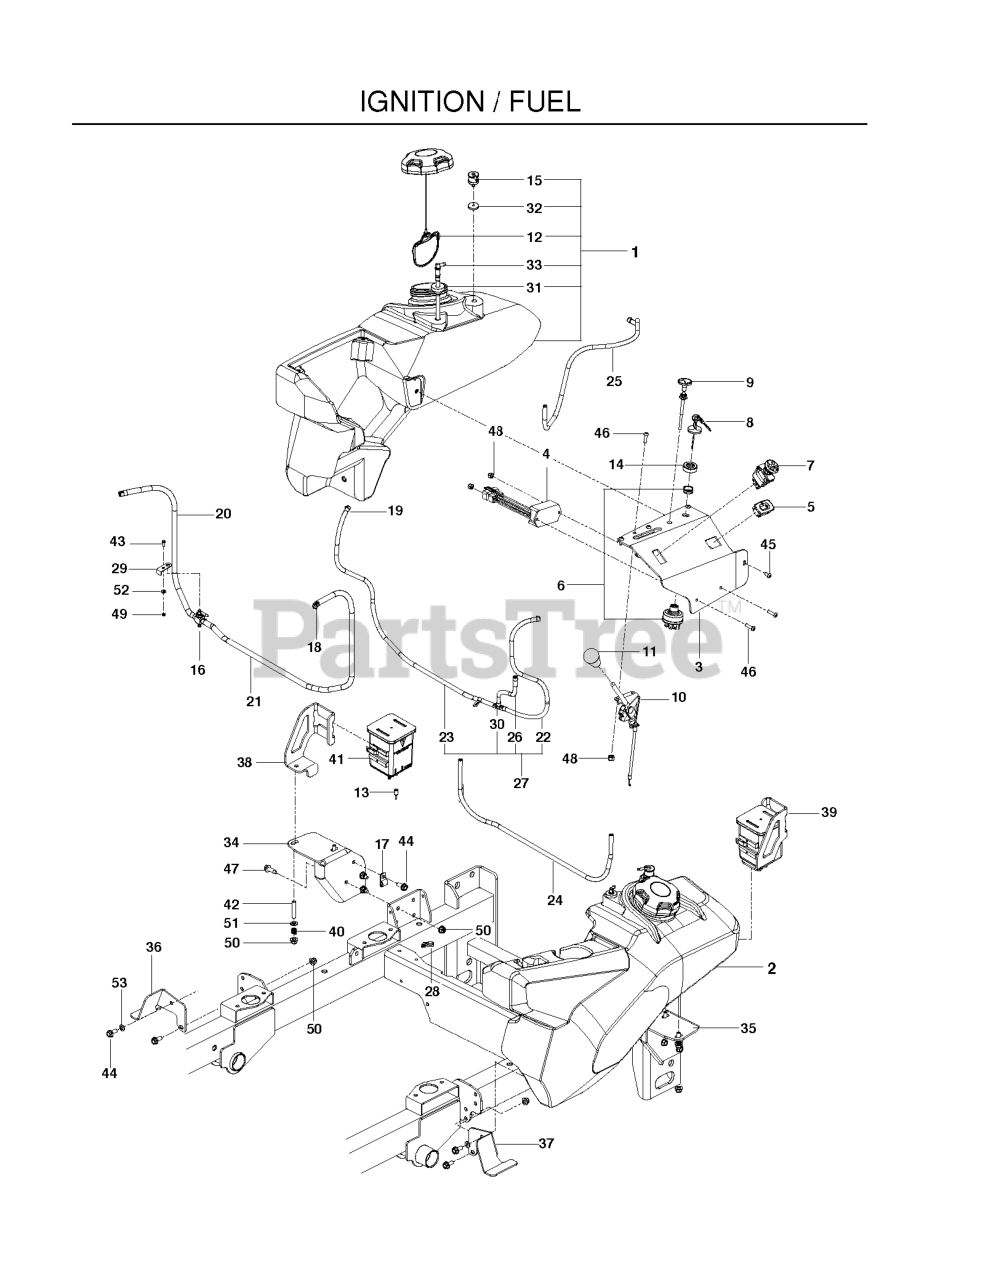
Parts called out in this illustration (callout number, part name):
1	RT FUEL TANK ASM EPA
2	LT FUEL TANK ASM EPA
3	PANEL.CONTROL.GAS.GRAY
4	TIMER, SEAT
5	HOUR METER
6	SWITCH, IGNITION, INDAK
7	SWITCH, PTO 10 AMP
8	KEY, IGNITION
9	CABLE, CHOKE, 48"
10	CABLE, THROTTLE, 46"
11	KNOB - SHIFT
12	CAP, FUEL
13	CAP, VINYL
14	CAP IGNITION NUT
15	VALVE.FUEL.CHECK
16	FUEL VALVE
17	DOUBLE TUBE CLAMP
18	HOSE CLAMP
19	CLAMP, HOSE
20	LINE, FUEL, 22"
21	LINE, FUEL, 38"
22	HOSE, 3/16" VAPOR, 21"
23	HOSE, VAPOR 3/16 X 39"
24	HOSE, VAPOR 3/16 X 30"
25	FUEL LINE 33"
26	HOSE, 3/16" VAPOR, 7-1/2"
27	ASSEMBLY, VAPOR LINE
28	TIE WRAP, 8-3/8", W/CLIP
29	BRACKET,FUEL VALVE, BLACK
30	TEE, FUEL LINE 3/16"
31	RUBBER GROMMET
32	GROMMET, CHECK VALVE
33	FITTING, FUEL
34	MOUNT, RT TANK, BLK
35	MOUNT, LT TANK, BLK
36	XX MOUNT, TANK, RT-BLK
37	MOUNT, TANK, LT-BLK
38	MOUNT, CANISATER, RT
39	MOUNT, CANISTER, LT
41	CANNISTER, CARBON
42	STUD, 5/16C
43	HCS 1/4C X 3/4 HCS
44	HHFS 5/16-18 X 3/4
45	SCR #10-24 X 3/8 SKT HD BLK OX
46	SCR #10-24 X .75 SKT HD BLK
47	RP BLT 5/16-18 X 1 THRD FORM D
48	NUT 10-24 NYLOC
49	JAM NUT 1/4C (2 2 PW01)
50	5/16-18 NYLOC FLANGE NUT
51	FLAT WASHER 5/16 SAE
52	WASHER 1/4 FLAT
53	WASH 5/16 DISC SPRING ZD
